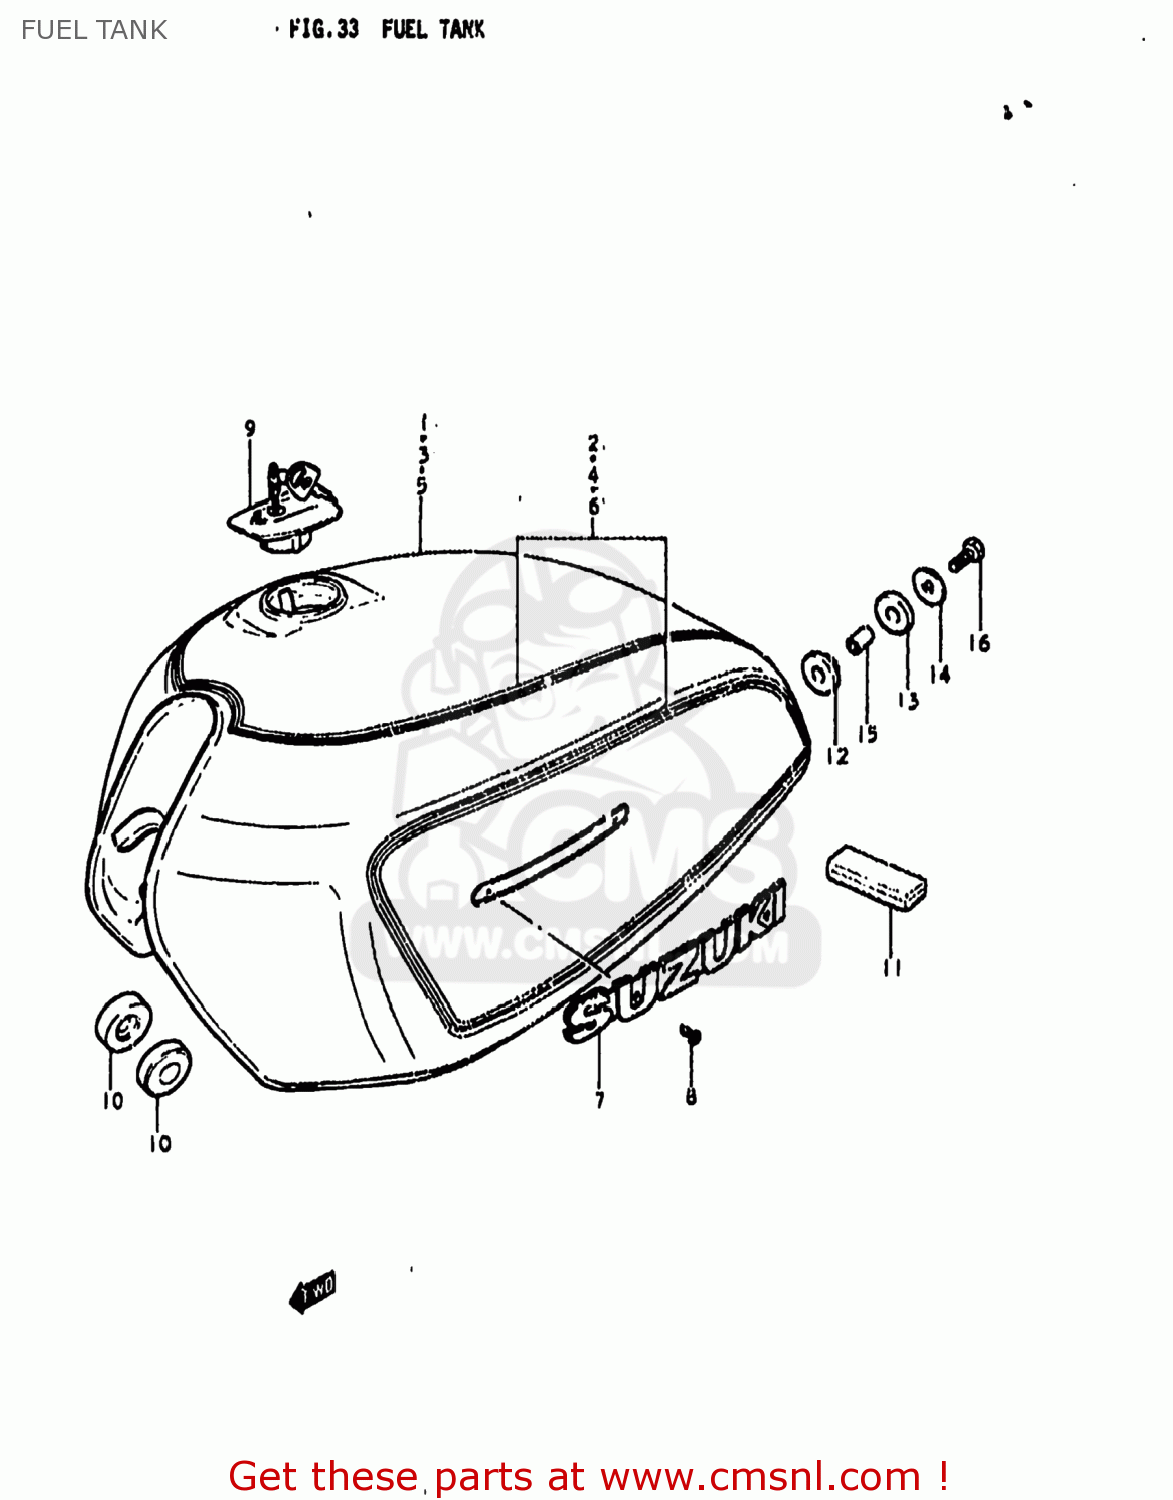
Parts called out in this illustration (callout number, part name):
1	TANK ASSEMBLY,FUEL
2	TAPE SET
3	TANK ASSEMBLY,FUEL
4	TAPE SET
5	TANK ASSEMBLY,FUEL
6	TAPE SET
7	EMBLEM,FUEL TANK
8	SCREW 3X6
9	CAP SET,FUEL TANK
10	CUSHION
11	CUSHION
12	CUSHION
13	CUSHION
14	WASHER (8.5X29X1.6)
15	SPACER(8.5X12X19)
16	BOLT (8X30)
